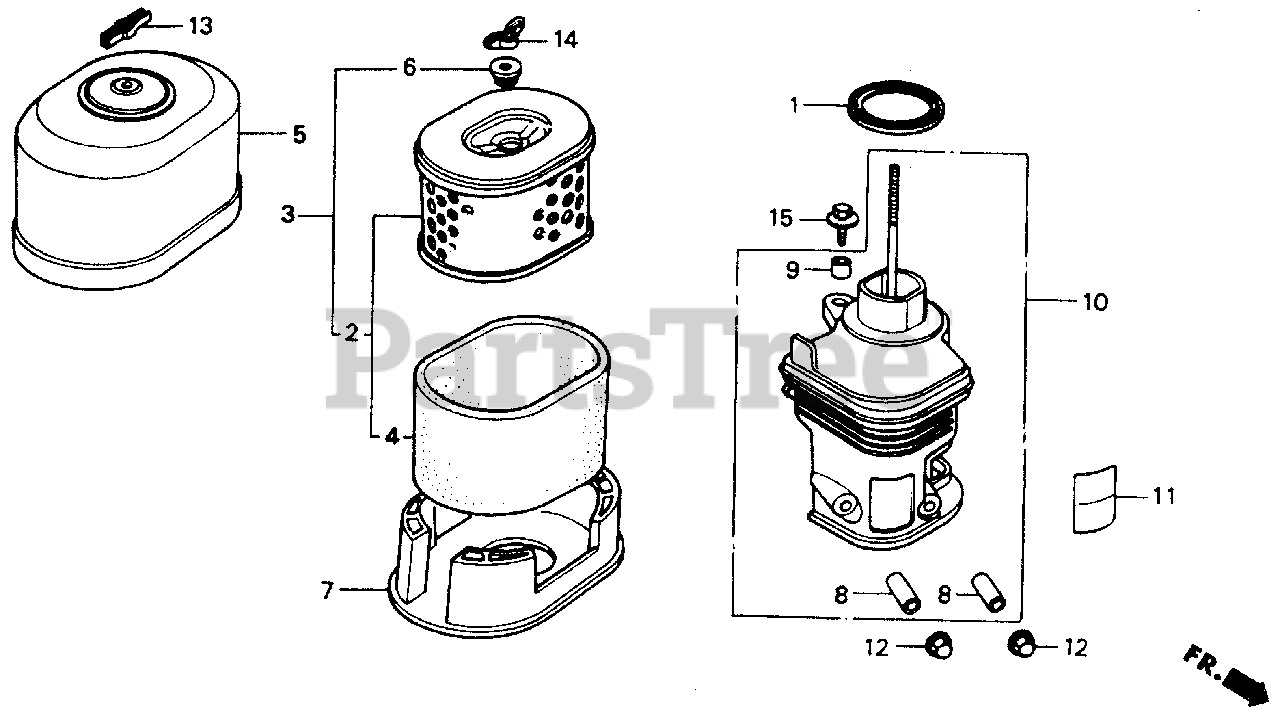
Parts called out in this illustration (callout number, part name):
1	GASKET, ELBOW
2	ELEMENT, AIR CLEANER
3	ELEMENT, AIR CLEANER
4	FILTER (OUTER)
5	COVER, AIR CLEANER (STD)
6	GROMMET, AIR CLEANER
7	NOSE, MUFFLER
8	COLLAR, AIR CLEANER
9	COLLAR B, AIR CLEANER
10	ELBOW SET, AIR CLEANER
10	ELBOW, AIR CLEANER
11	MARK, CHOKE (EXTERNAL)
12	NUT, CAP (6MM)
13	WINGNUT, AIR CLEANER COVER
14	WINGNUT, TOOL BOX SETTING
15	BOLT-WASHER (6X20)
